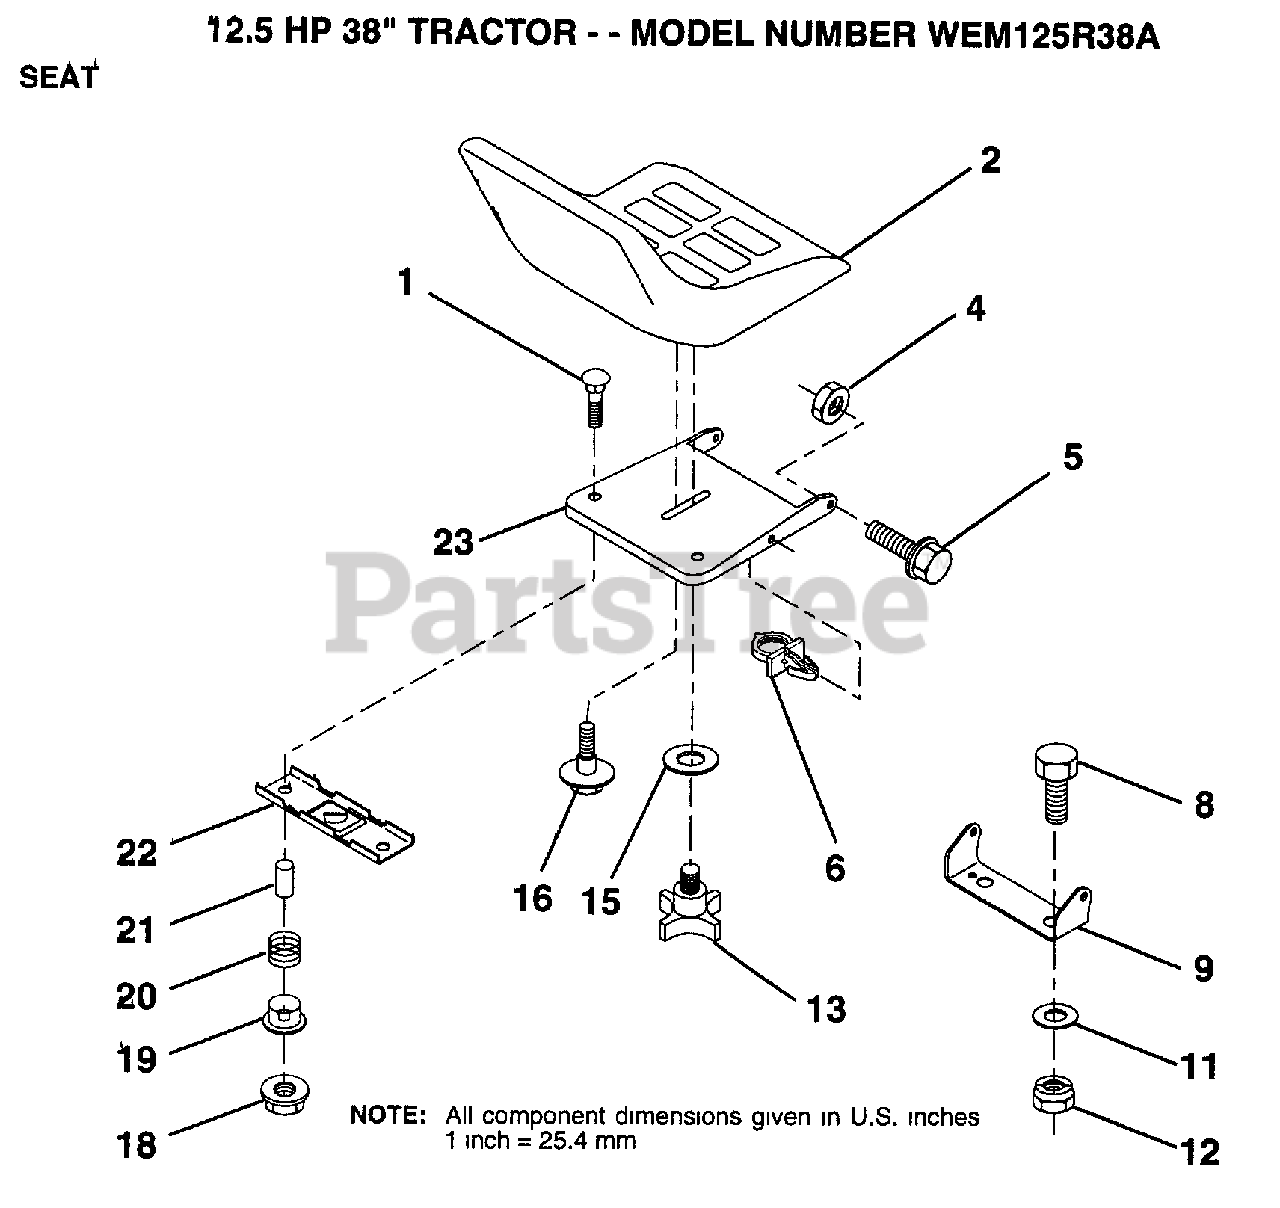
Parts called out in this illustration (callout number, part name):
4	NUT
5	BOLT.SHLD.5/16-18
6	CLIP PUSH - IN
8	BOLT
9	BRACKET PVT SEAT
11	WASHER
12	NUT
13	"KNOB 1/2"" YT"
15	WASHER, 17/32X1-3/16X12 GA
16	"BOLT,SHOULDER"
19	BUSHING
20	SPRING
21	SPLIT SPACER
22	BRKT SWITCH
